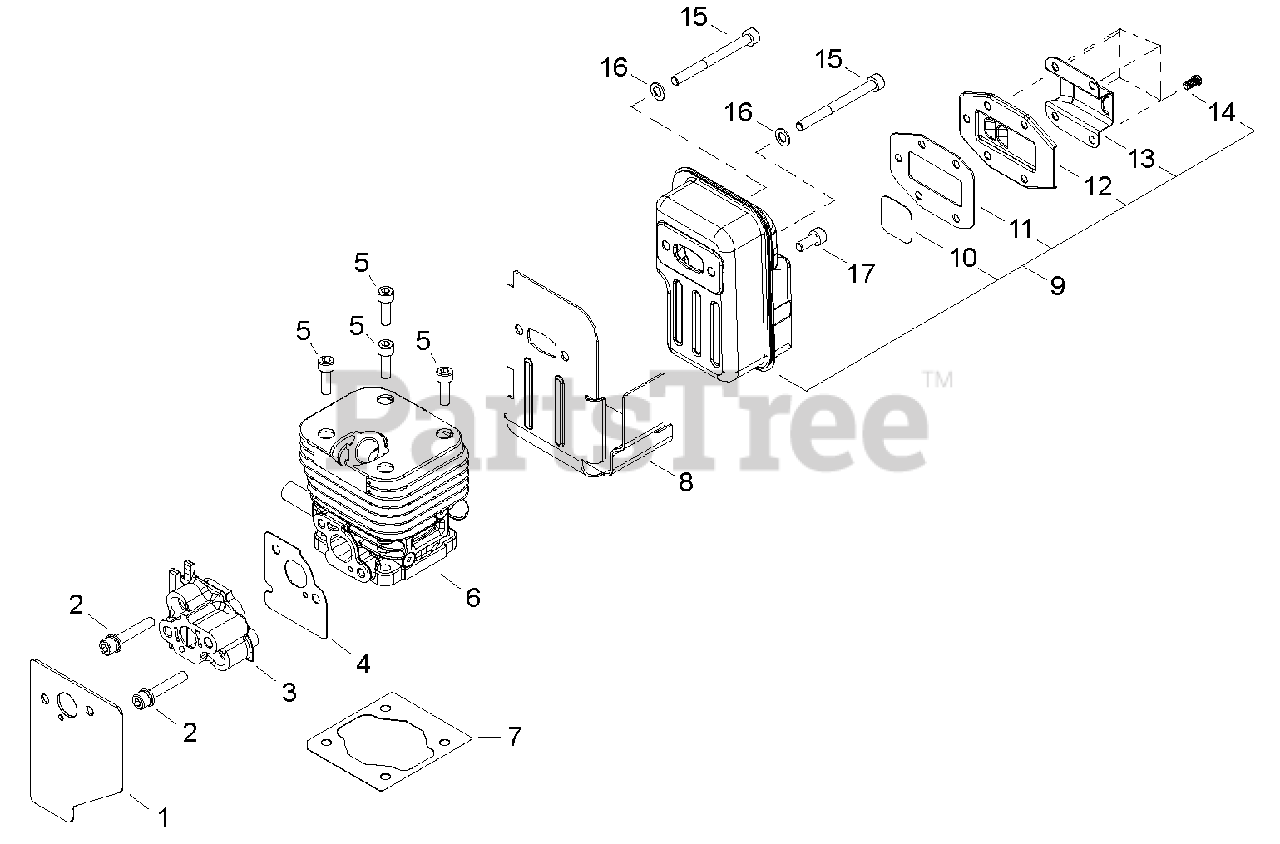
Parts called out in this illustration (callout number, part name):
1	GASKET, INTAKE
2	SCREW - 5X30
3	INSULATOR
4	GASKET, INTAKE
5	SCREW - 5X16
6	CYLINDER
7	GASKET, CYLINDER
8	DEFLECTOR, HEAT
9	MUFFLER ASSY
10	SCREEN, SPARK ARRESTOR
11	GASKET, EXHAUST
12	GUIDE, EXHAUST - INNER
13	GUIDE, EXHAUST - OUTER
14	SCREW - 4X8
15	SCREW - 5X55
16	WASHER - 5
17	SCREW - 5X12
